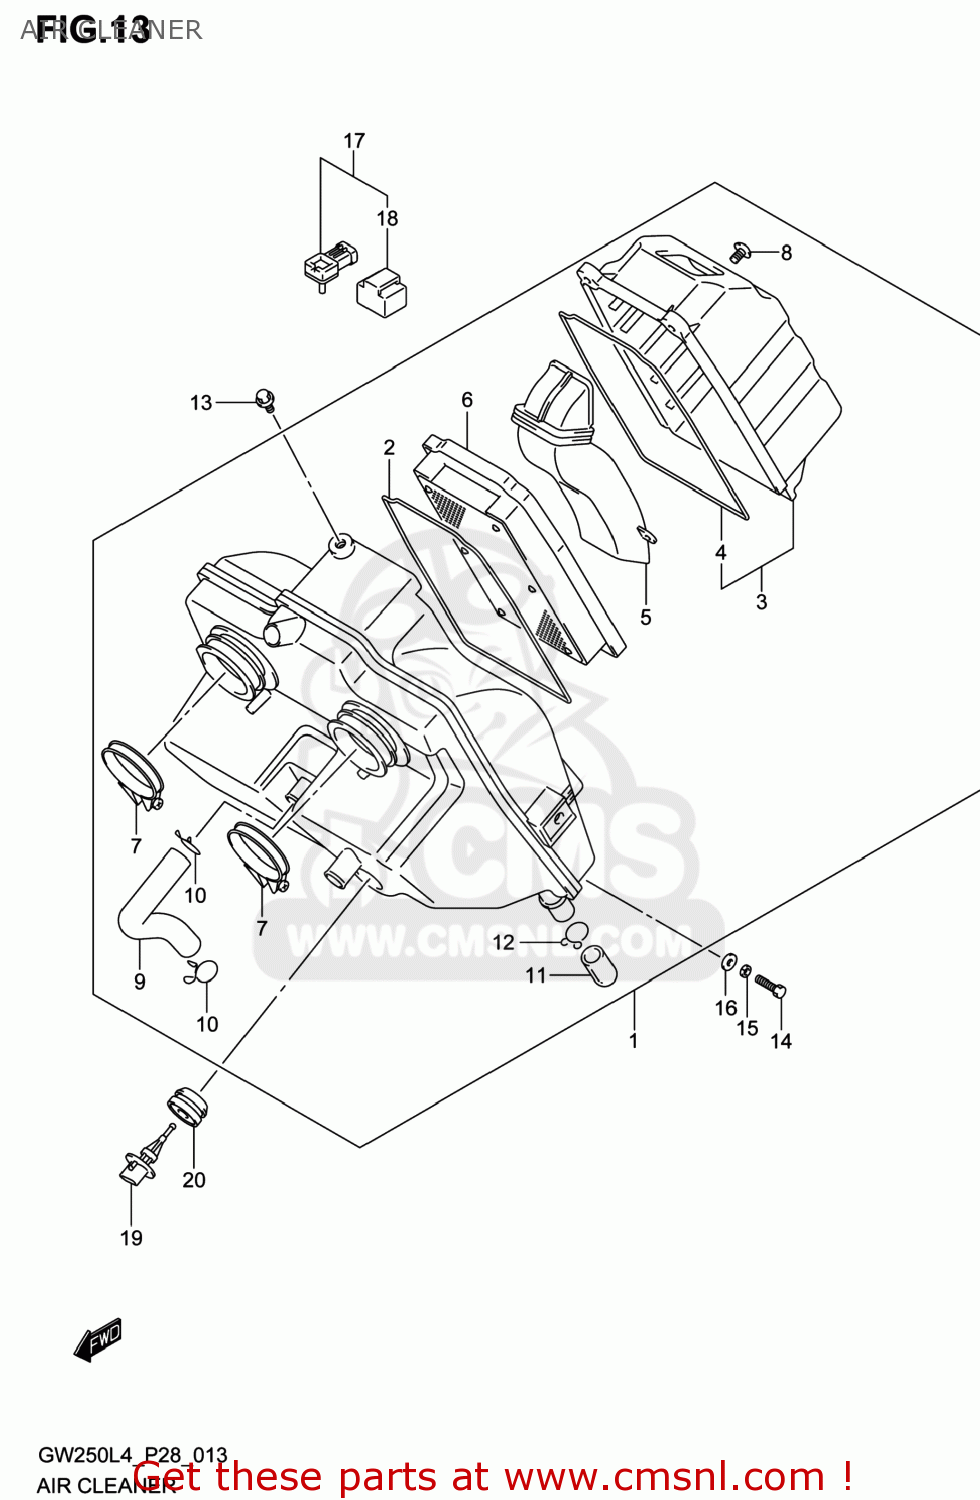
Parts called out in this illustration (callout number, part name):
1	CLEANER ASSY,AIR
2	GASKET,AIR CLEANER (NAS)
3	CAP,AIR CLEANER
4	GASKET,AIR CLEANER (NAS)
5	TUBE,INLET
6	FILTER ASSY
7	CLAMP
8	SCREW
9	TUBE,BREATHER
10	CLIP
11	PLUG,DRAIN
12	CLIP
13	BOLT
14	BOLT
15	WASHER,LOCK
16	WASHER(6.5X20X1.2)
17	SENSOR,BOOST
18	COVER
19	SENSOR,INLET AIR TEMP
20	GROMMET,AIR TEMP SENSOR
